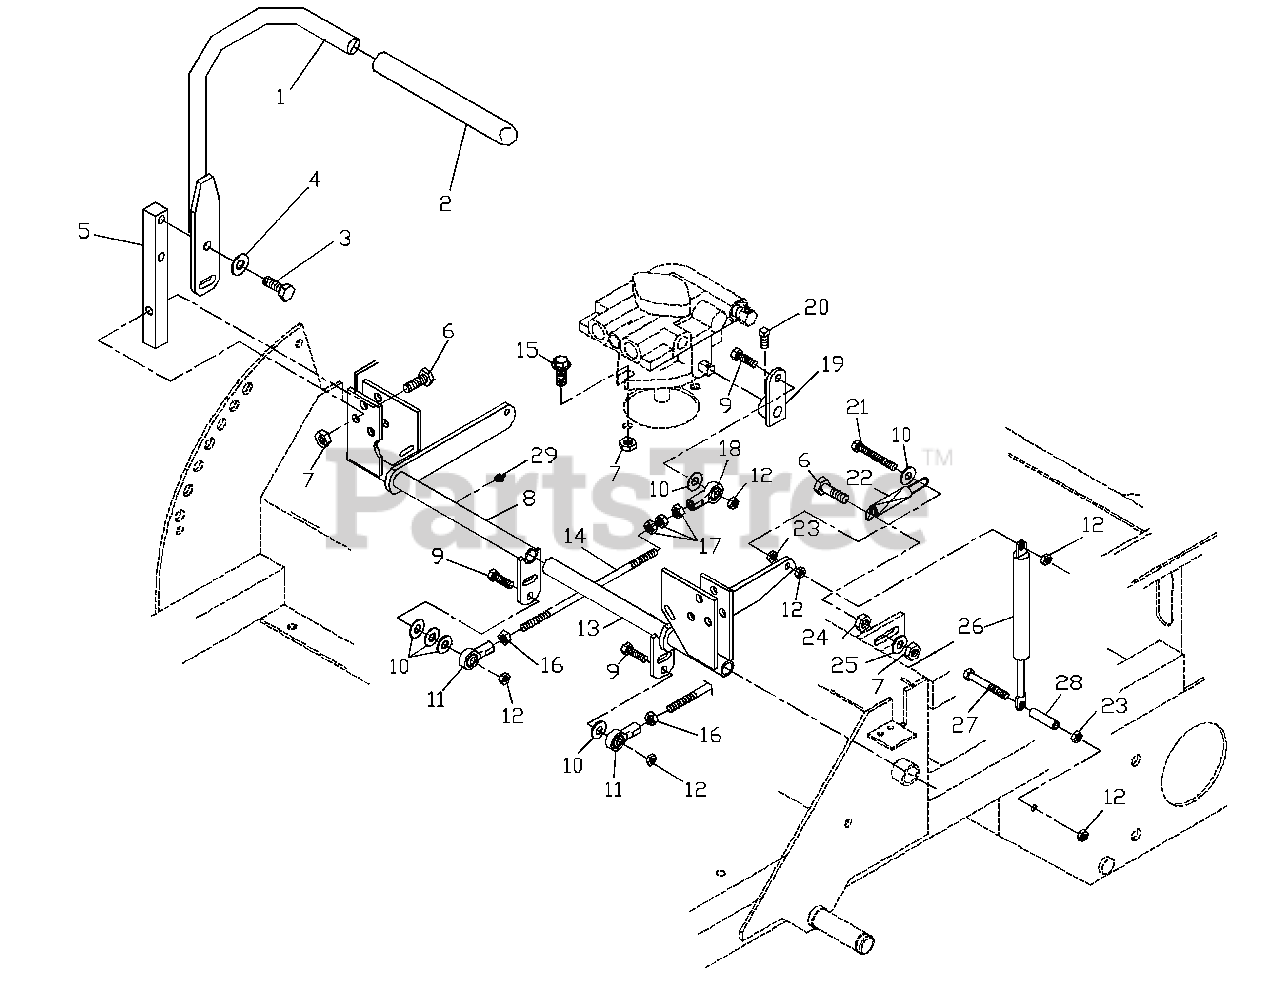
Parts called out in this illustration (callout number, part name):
1	CONTROL LEVER WLDMT
3	HCS 3/8C X 1
4	3/8 DISC SPRING WASHER
5	CONTROL ARM
6	HCS 3/8C X 1 1/2
7	NUT 3/8C CENTERLOCK
8	CONTROL WELDMENT, RIGHT
9	HCS 5/16C X 1 1/4
10	WASHER 5/16 FLAT
11	BALL JOINT, LEFT HANDED
12	NUT 5/16C CENTERLOCK
13	CONTROL WELDMENT, LEFT
14	PUMP CONTROL LINK
15	HCS 3/8C X 1 SERRATED HEAD
16	NUT 5/16F LEFTHAND
18	BALL JOINT, RIGHTHAND
19	CONTROL ARM, PUMP
20	5/16C X 5/8 SQ. HEAD
21	TAPBOLT 5/16C X 2 1/4
23	5/16C WHIZ NUT
24	3/8C WHIZ NUT
25	WASHER 3/8 FLAT
27	HCS 5/16C X 2 3/4 GRADE 8
29	ZERK
